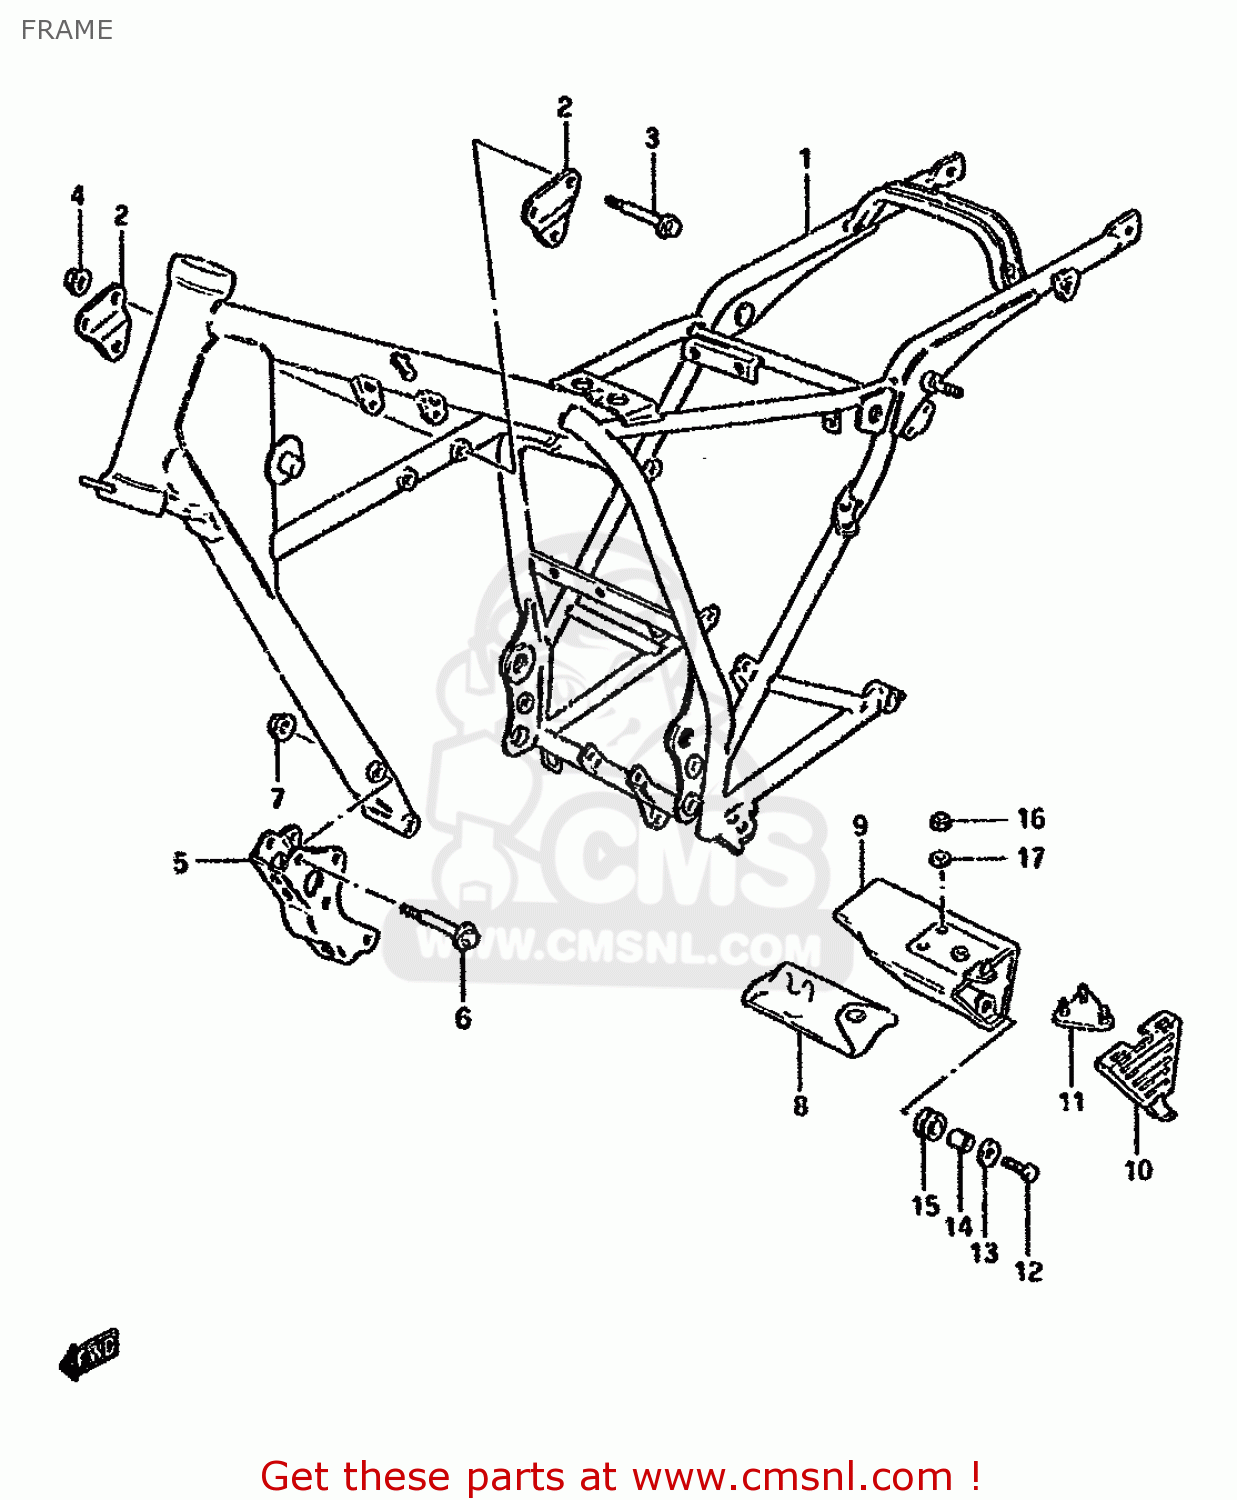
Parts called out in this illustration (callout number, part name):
1	FRAME
2	PLATE,ENGINE MOUNTING
3	BOLT
4	NUT
5	BRACKET,ENGINE MOUNTING LWR
6	BOLT
7	NUT
8	TOOL SET
9	BOX,TOOL
10	CAP,TOOL BOX
11	PLATE,TOOL HOLDER
12	BOLT
13	WASHER (6.5X20X1.2)
14	SPACER(6.1X9X7.5)
15	CUSHION
16	NUT
17	WASHER
